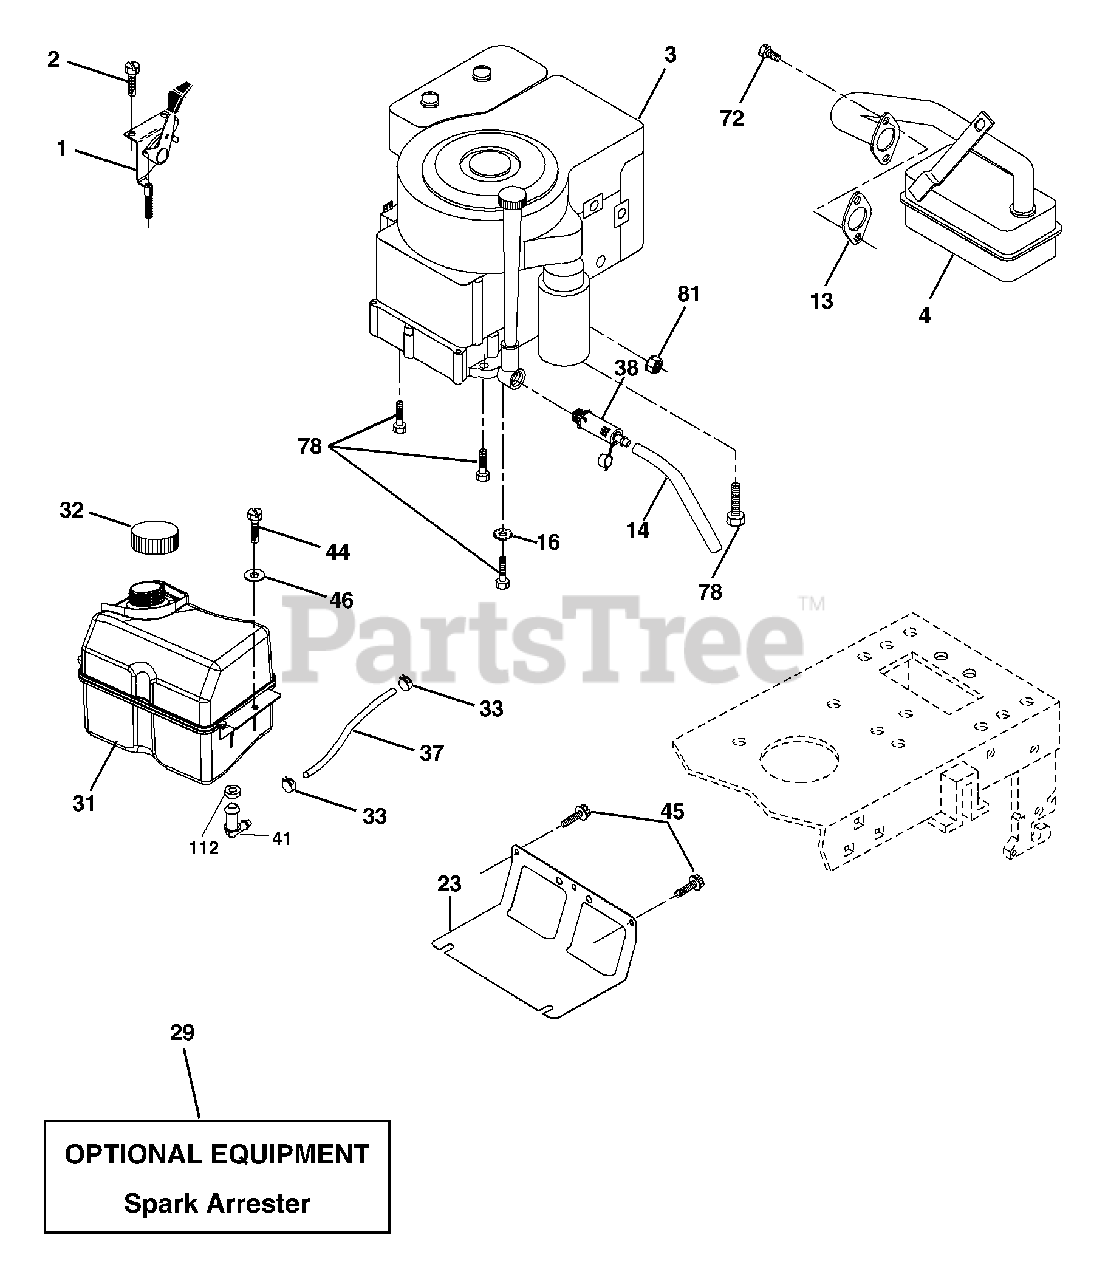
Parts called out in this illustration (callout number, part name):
1	Control Th/ch Flag
2	Screw Hex Thd Cut 1/4-20 x 1/2
4	Muffler
13	Gasket Eng
14	Tube Drain Oil Easy
16	Washer Lock Ext Tooth 3/8
23	Shield Brn/Dbr Guard
29	Kit Spark Arrestor (Flat Scrn)
31	Tank Fuel Front
32	Cap Asm Fuel W/sym Vented
33	Clamp Hose Black
37	Line Fuel 20"
38	Plug Drain Oil Easy
41	Stem Tank Fuel
44	Screw Hexwsh Thdrol 1/4-20 x 3/4
45	Screw Hexwsh Thdr 3/8-16 x 3/4
46	Washer 9/32 X 7/8 X 16 Ga
72	Screw Socket Head 5/16-18 x 1
78	Screw 3/8-16 x 1-1/4
81	Nut Keps Hex 1/4-20 UNC
112	Bushing
